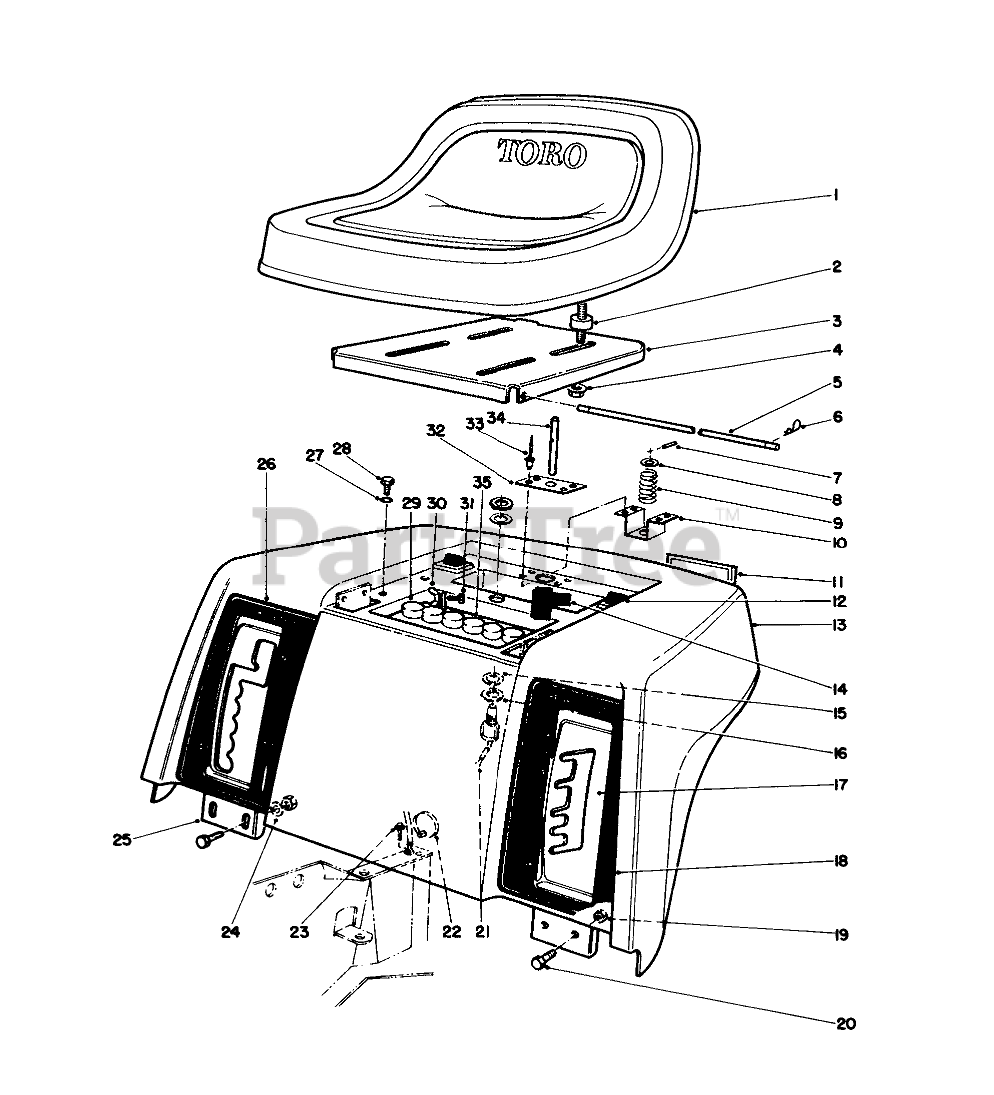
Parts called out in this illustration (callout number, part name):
2	ISOLATER-SEAT
3	SEAT SUPPORT R
4	NUT-HF
5	PIVOT-SEAT
6	PIN-COTTER
7	PIN-SPRING
8	WASHER-FLAT
9	COMPRESSION SPRING
10	Bracket-Spring
11	REFLECTOR
12	SEAT BUMPER
13	Body-Rear Assembly (Incl. Ref. #18 & 26)
14	BOOT-TERMINAL
15	WASHER-FLAT
16	NUT-HH
17	Quadrant Height of Cut
18	Decal-Height of Cut
19	NUT-LOCK, NI
20	SCREW-HH
21	Switch-Seat (Incl. Ref. #16)
22	TIE-CABLE
23	SCREW-HWHTF
24	WASHER-PLAIN
25	DETENT PLATE B
26	Decal-Transmission
27	WASHER
28	SCREW-HWHTF
29	Battery
30	NUT-WING
31	SCREW-HH
32	RETAINER PLATE
33	RIVET-BLIND
34	Rod-Plunger
35	NON-VENTED BATTERY CAP
